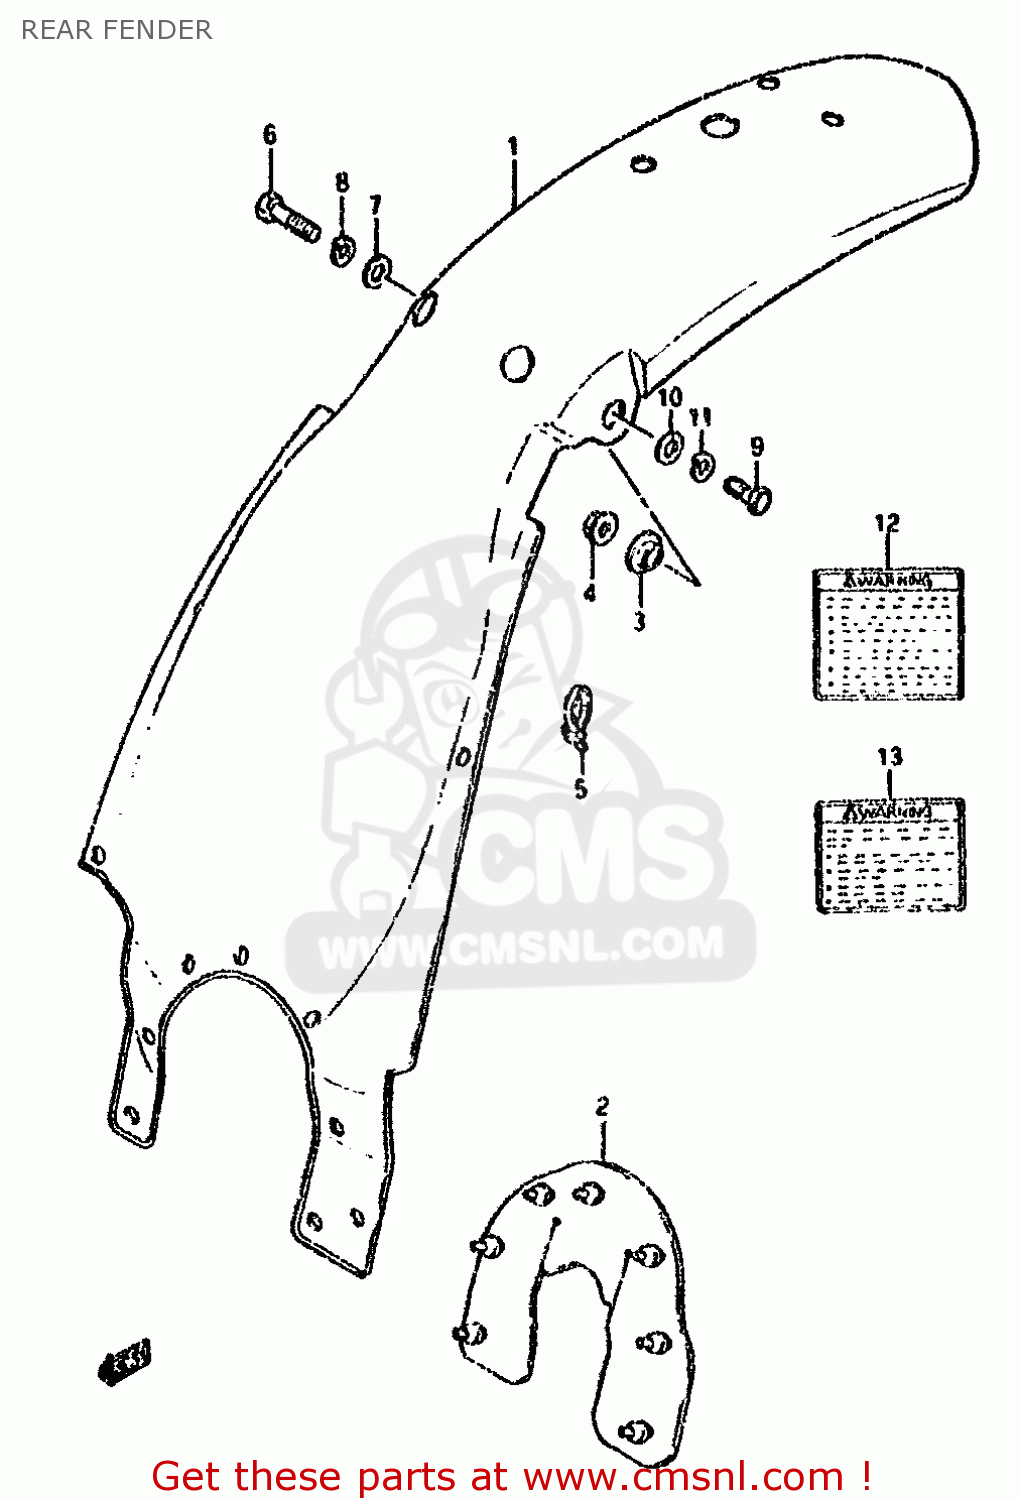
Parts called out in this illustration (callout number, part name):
1	FENDER,RR
2	MUDGUARD,RR FENDER
3	WASHER
4	NUT
5	CLAMP
6	BOLT
7	WASHER (8.5X29X1.6)
8	LOCK WASHER
9	BOLT
10	WASHER
11	WASHER,LOCK,8.
12	LABEL (WARNING)
13	LABEL
14	MANUAL,OWNER'S
